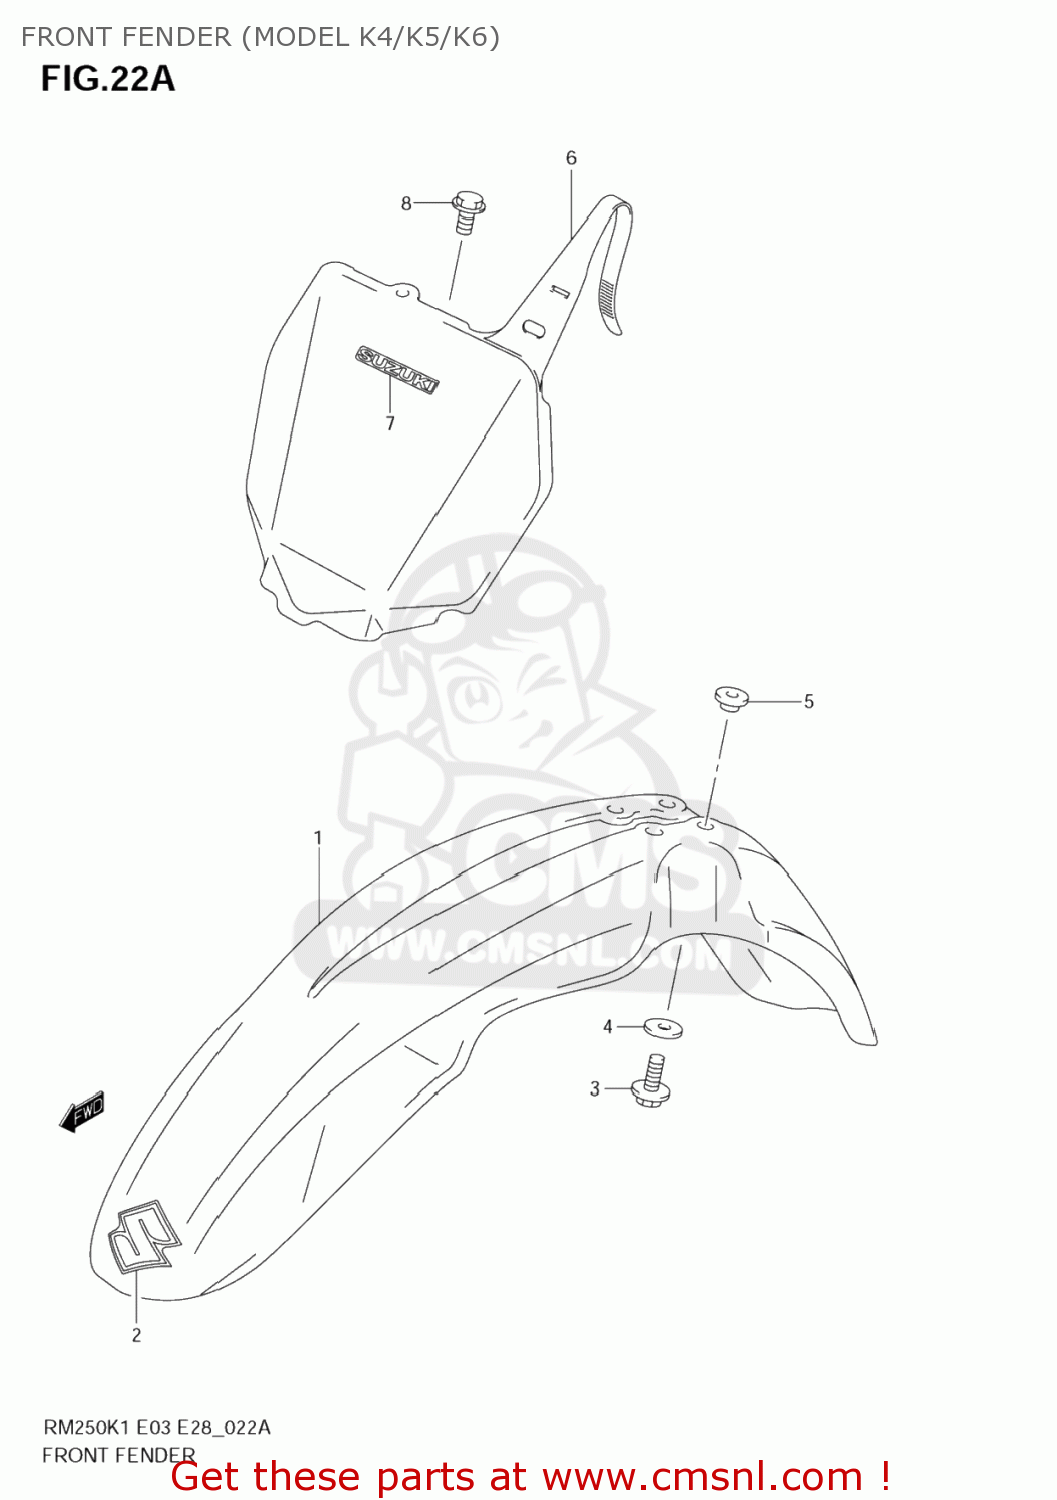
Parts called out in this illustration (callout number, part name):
1	FENDER,FR
2	EMBLEM,S
3	BOLT
4	WASHER(6.5X28X1.6)
5	WASHER
6	PLATE,NUMBER F
7	EMBLEM,HEADLAMP COVER
8	BOLT(6X12)
